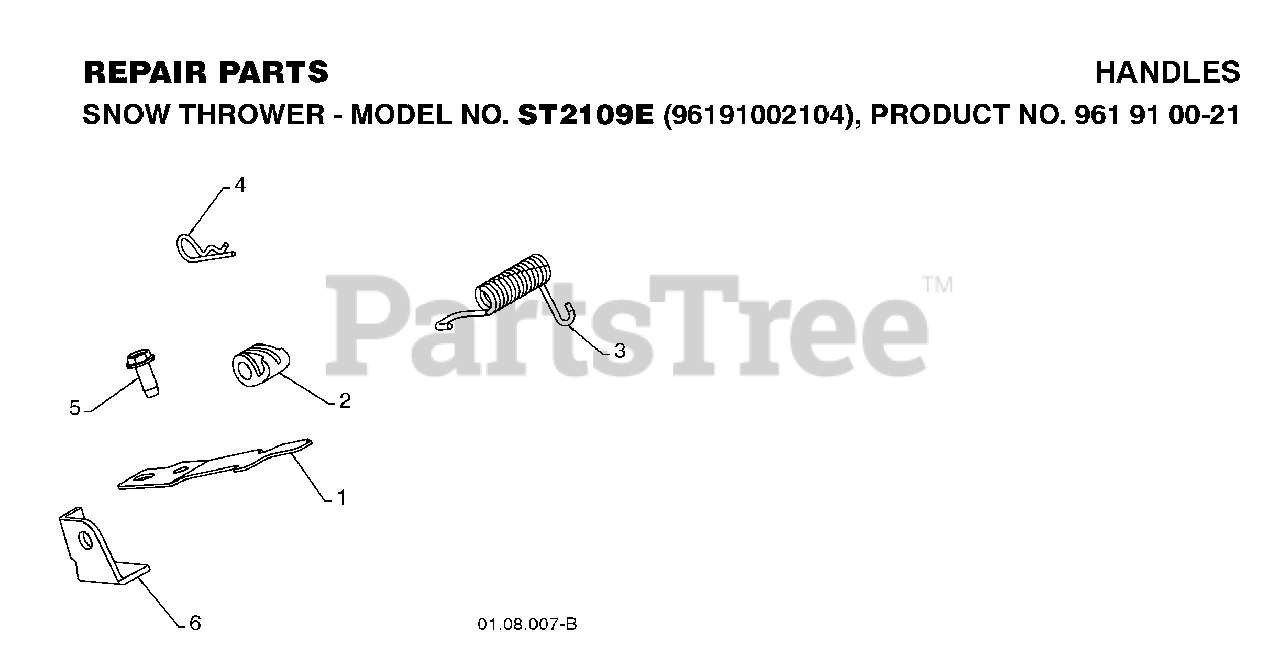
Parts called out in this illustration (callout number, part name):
1	SPRING.INTERLOCK
2	RP CAM.INTERLOCK.RELEASE
3	RP SPRING, TORSION
4	SPRING RETAINER
5	SCREW 14-20 X 5/8
6	STOP.INTERTLOCK.SPRING
